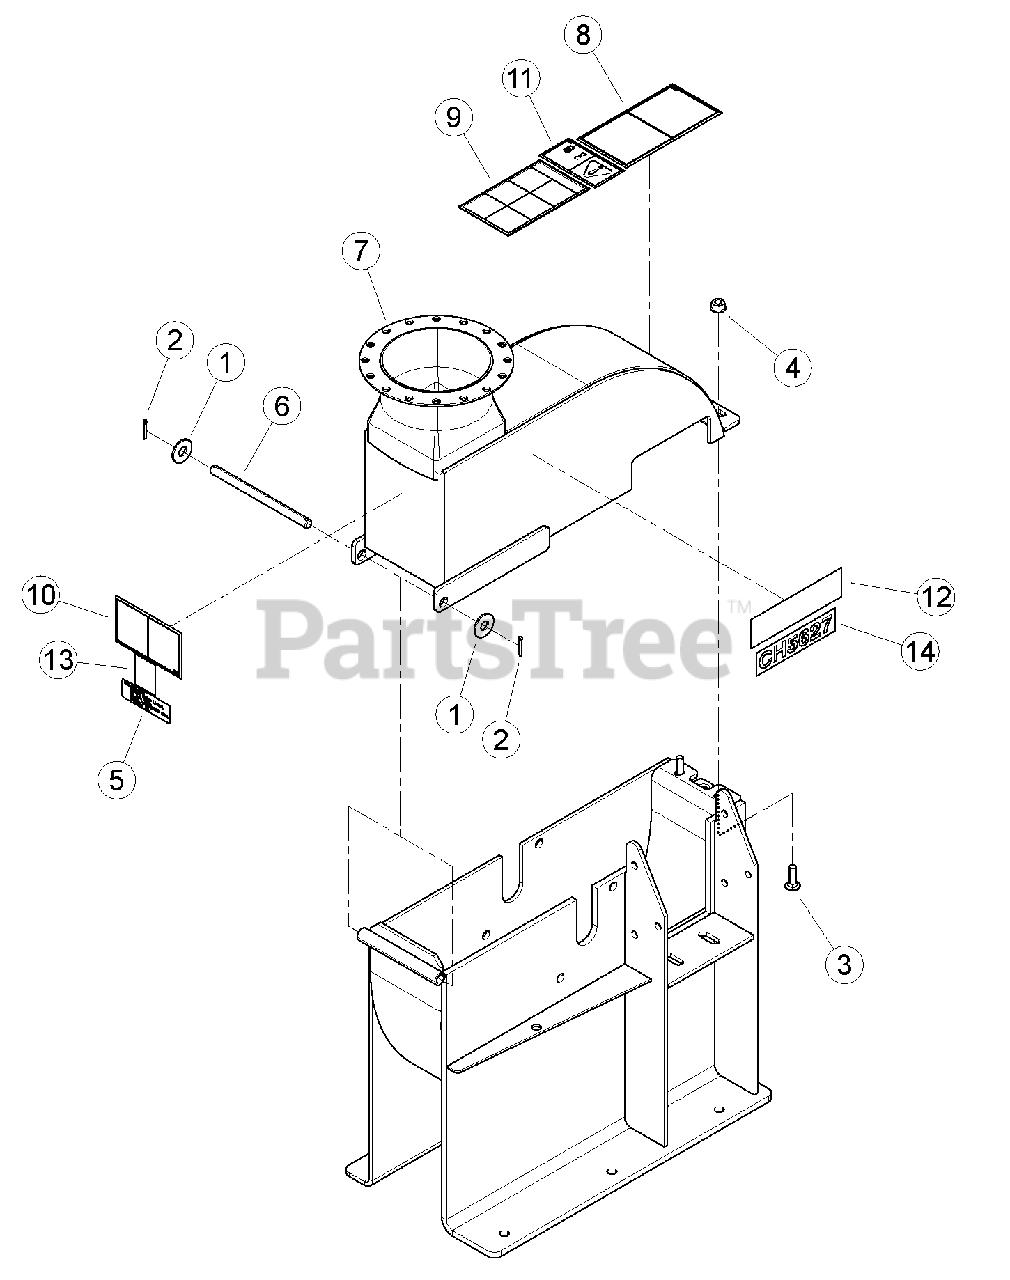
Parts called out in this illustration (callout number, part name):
1	WASHER, 1/2 FLAT
2	PIN, 1/8 X 1.00 ZP COTTER
3	BOLT, 3/8-16 X 1-1/4 GR5 CRG
4	NUT, 3/8-16 NYLOCK FLANGE
5	DECAL, ATLANTIC BRIDGE LTD INFO (CE COMPLIANT ONLY)
6	SHAFT, CHIPPER TOP PIVOT
7	ASSEMBLY, CHIPPER TOP W/ DECALS
8	DECAL, KNIFE ACCESS ISO
9	DECAL, OPERATING INSTRUCTIONS ISO
10	DECAL, DISCHARGE ISO
11	DECAL, MAINTENANCE ISO
12	DECAL, ECHO BEARCAT 6.82 X 1.90
13	DECAL, ECHO BEARCAT QR CODE
14	DECAL, MODEL CH5627
